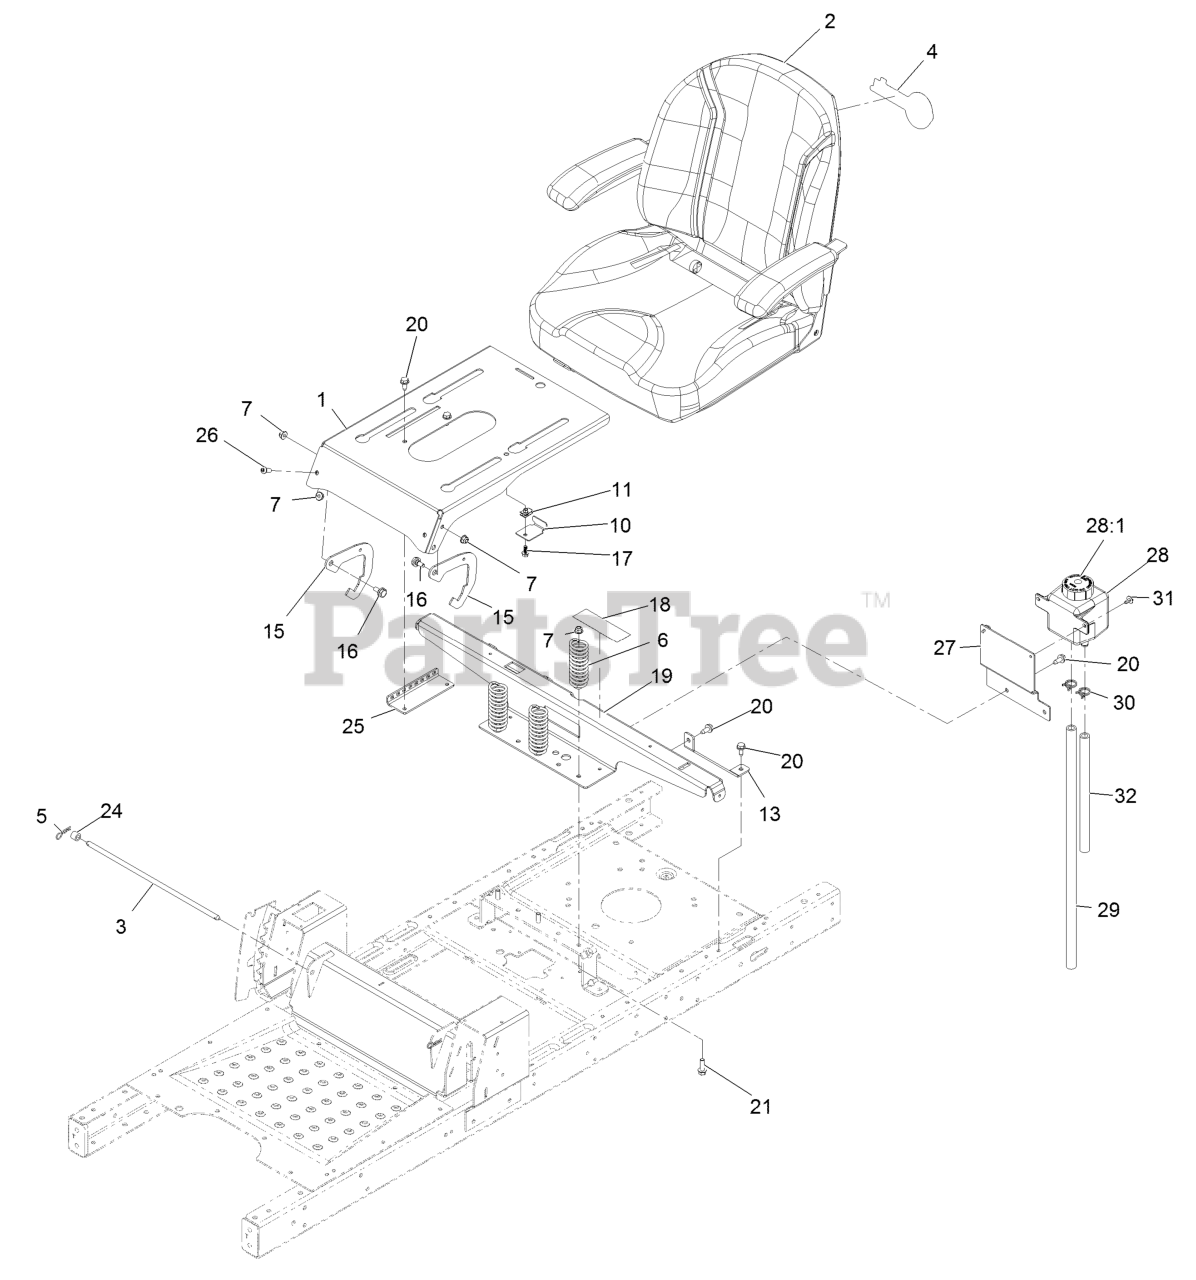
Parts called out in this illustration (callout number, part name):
2	SEAT ASM, EXMARK
3	ROD-STOP
4	DECAL-EXMARK LOGO
5	PIN-COTTER
6	SPRING-COMPRESSION
7	NUT-HF, NI
10	BRACKET-STOP, SEAT
11	Nut-Retainer-Panel 1/4-20
13	SUPPORT-TANK, REAR
15	PLATE-STOP
16	SCREW-SHOULDER
17	SCREW-HHF
18	DECAL-SERVICE, CE
19	SUPPORT-POD, WIDE
20	Screw-HWH 5/16-18 X 3/4 Tf
21	SCREW-HHF
24	BUSHING-LEVER, LIFT
25	BRACKET-LATCH, SEAT
26	SCREW-HSBH
27	MOUNT-TANK
28	TANK-HYD
28:1	CAP-RESERVOIR, HYD
29	HOSE-OVERFLOW
30	CLAMP-HOSE
31	SCREW-HHFTF
32	HOSE-OVERFLOW
